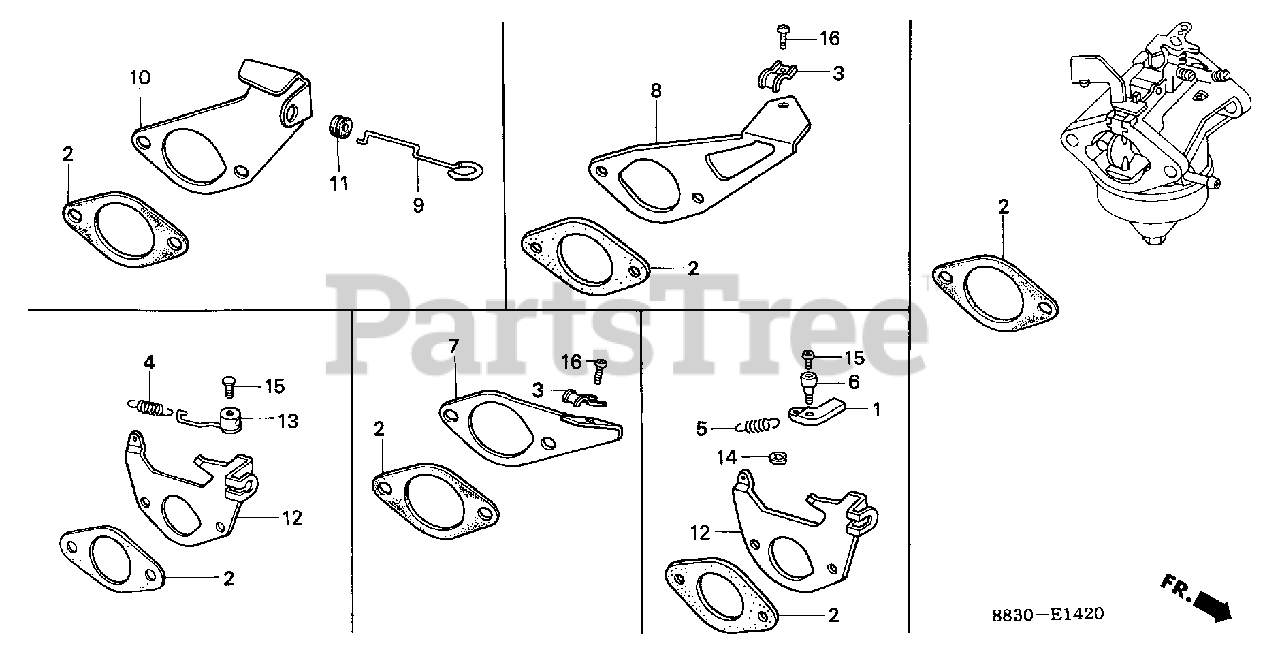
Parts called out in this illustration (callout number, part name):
2	GASKET, AIR CLEANER
9	ROD, CHOKE CONTROL
10	STAY, CHOKE CONTROL
11	GROMMET, CHOKE ROD
